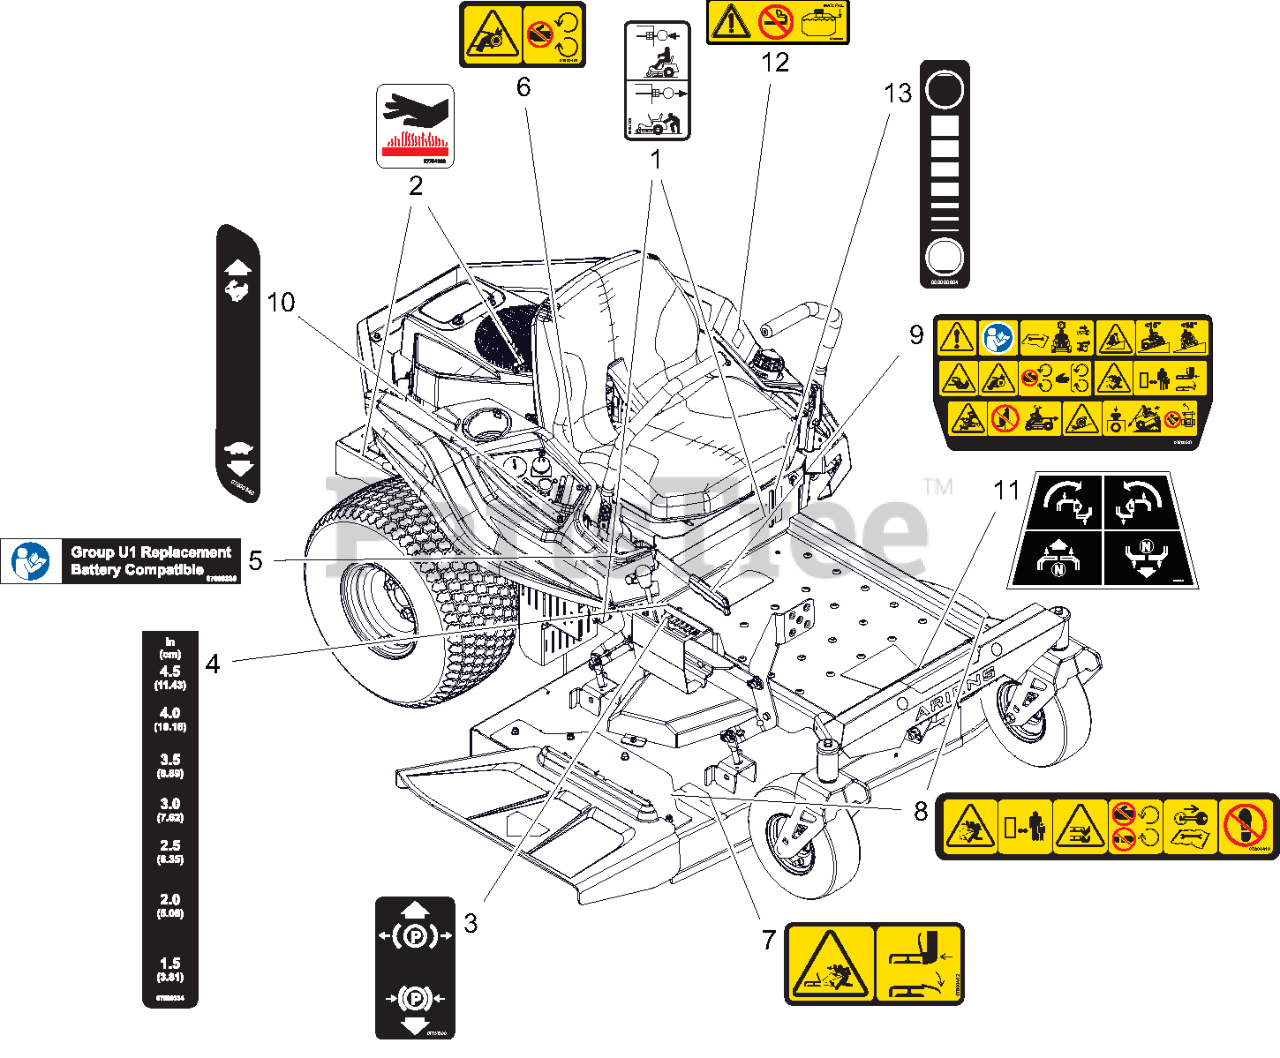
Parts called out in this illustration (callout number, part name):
1	DECAL, TRANSMISSION DISCONNECT
2	DECAL, HOT SURFACE
3	DECAL, PARKING BRAKE LEVER
4	DECAL, HEIGHT OF CUT
5	DECAL, U1 BATTERY REPLACEMENT
6	DECAL, SAFETY - GUARDING
7	DECAL, SAFETY - DECK GUARDING
8	DECAL, DECK SAFETY
9	DECAL, MAIN SAFETY
10	DECAL, DASH DECAL
11	DECAL, STEERING
12	DECAL, FUEL WARNING
13	DECAL, FUEL LEVEL
